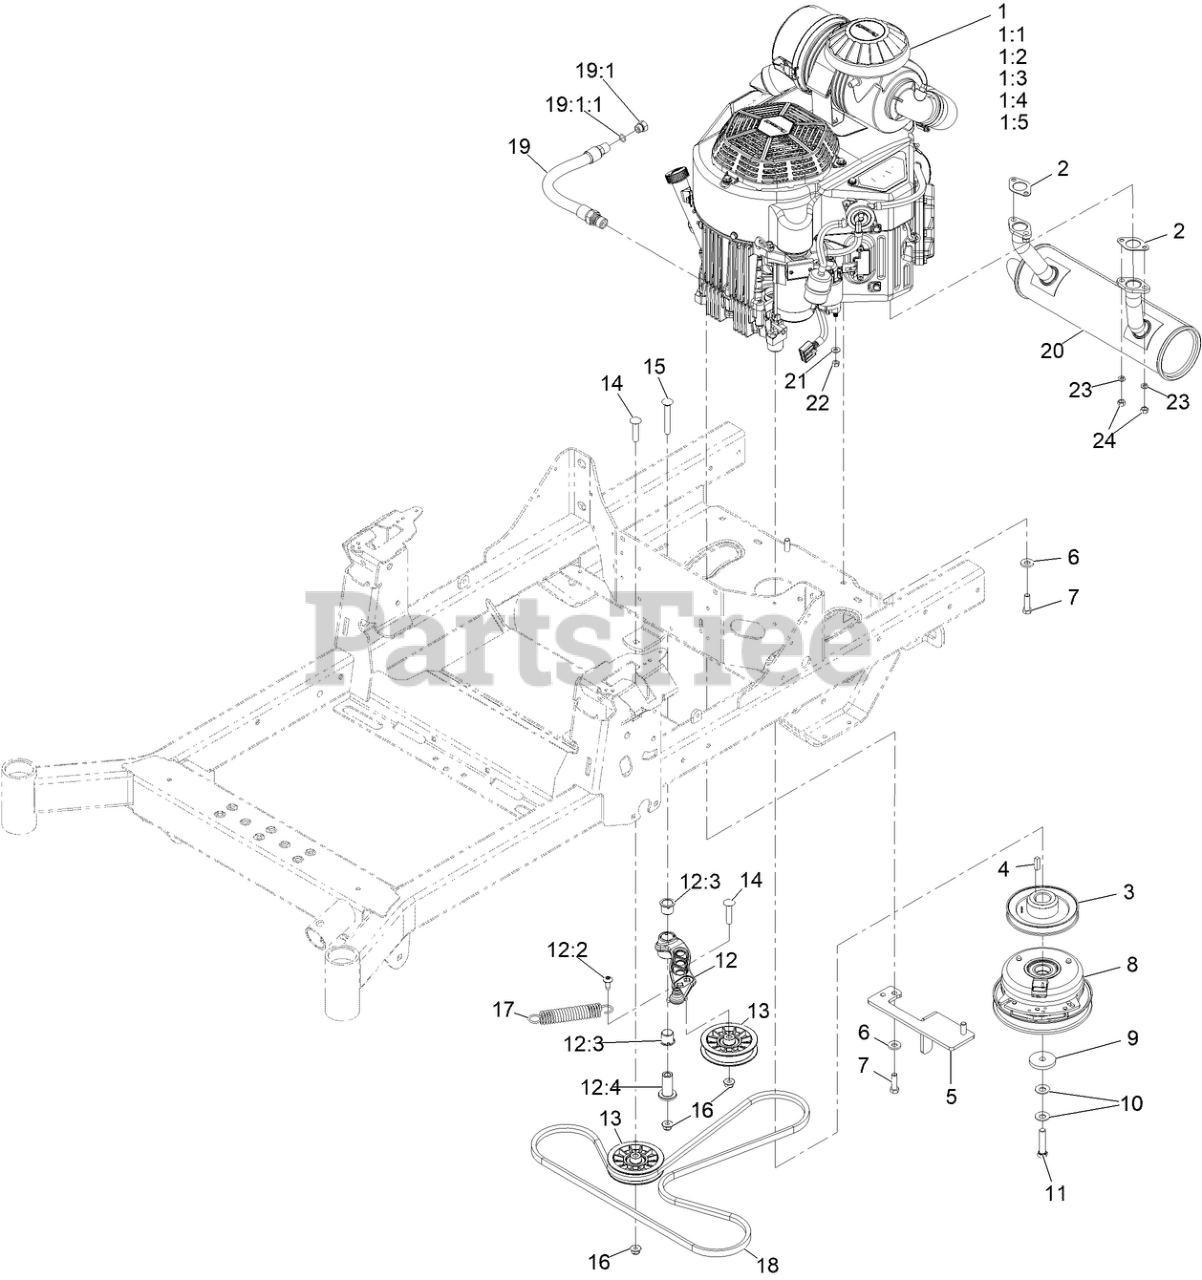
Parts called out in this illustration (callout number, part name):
2	GASKET-EXHAUST
3	SHEAVE, ENGINE
5	Anchor-Clutch
6	WASHER-BELLEVILLE
7	SCREW-HH
9	WASHER-CLUTCH
10	WASHER-SPRING
11	SCREW-HH W/LOCTITE
12	ASM, PUMP IDLER
12:2	SCREW, TAPTITE
12:3	BUSHING, IGUS
12:4	Spacer, Idler Pivot
13	PULLEY-FLAT IDLER
14	SCREW-CARR
15	SCREW-CARR
16	NUT-HF, NI
17	SPRING-EXTENSION
18	BELT-V
19	ENGINE OIL DRAIN HOSE ASM
19:1	PLUG-HH
19:1:1	O-RING
20	MUFFLER, KAWASAKI
21	WASHER-FLAT
22	NUT-HEX
23	WASHER-LOCK
